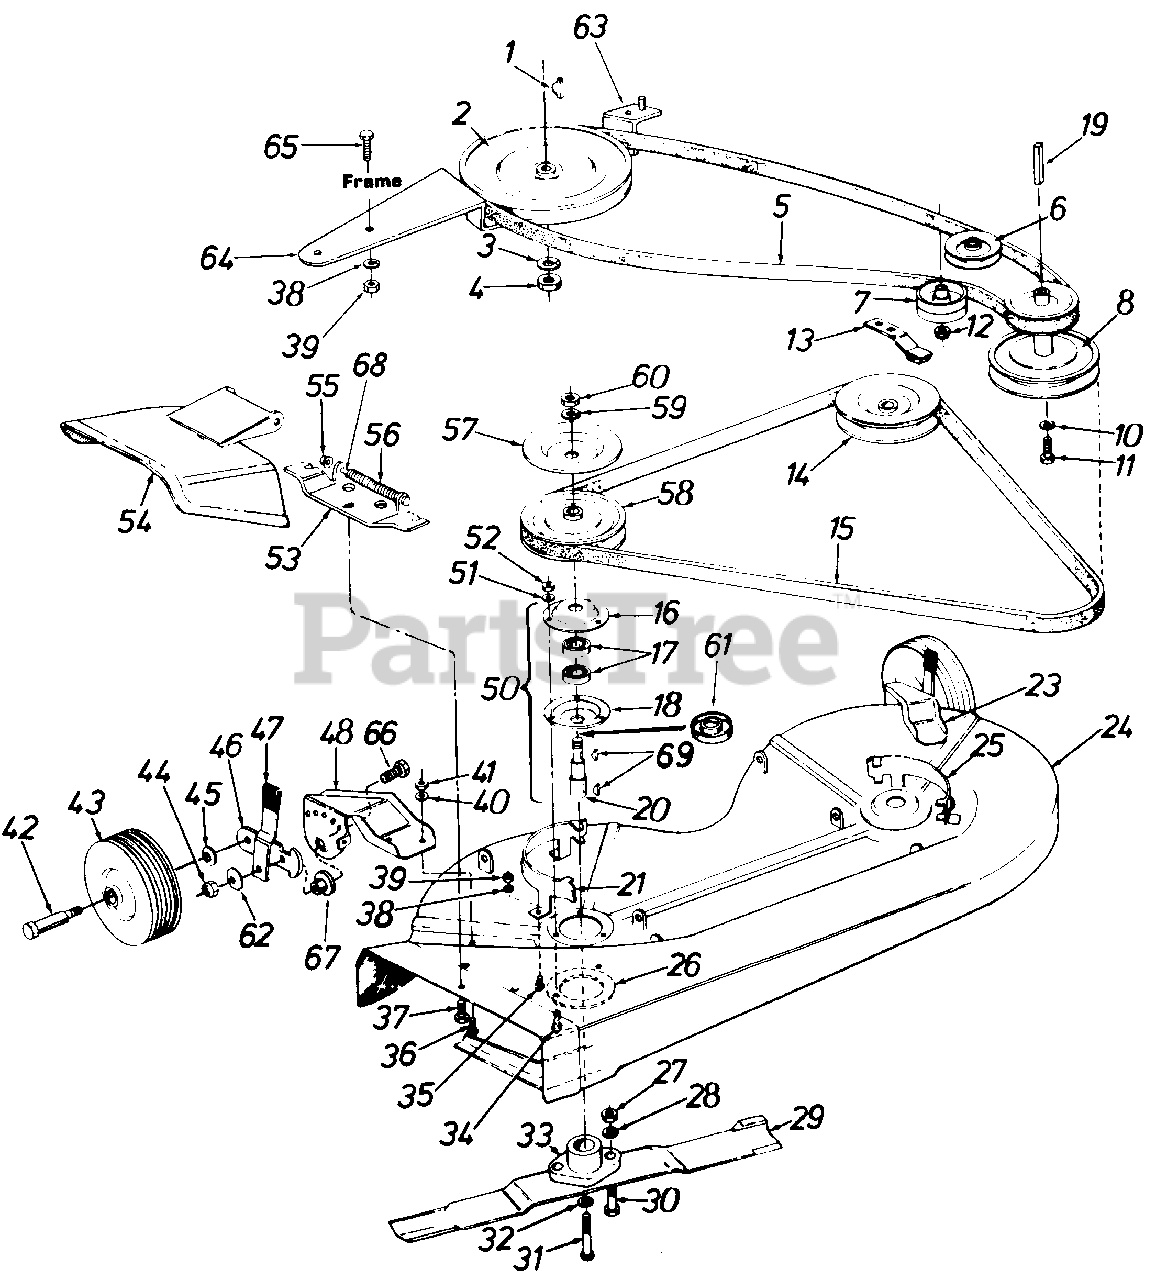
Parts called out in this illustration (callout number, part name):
1	#4 Hi-Pro Key 3/32 x 5/8" Dia.
2	Transmission Split Pulley .50 I.D.
3	L-Wash. 1/2" I.D.*
4	Hex Jam Nut 1/2-20 Thd.
5	"V" Belt 1/2 x 62" Lg.
6	"V" Idler 3.06 O.D.
7	"P" Flat Idler 2.75 O.D.
8	Two-Step Engine Pulley
10	L-Wash. 7/16" I.D.
11	Hex Bolt 7/16-20 x 1.0" Lg.
12	Hex Ins. L-Nut 3/8-24 Thd.
13	Blade Brake Ass'y.
14	Deck Pulley 4.75 O.D.
15	"V" Belt 21/32" x 64" Lg.
16	H ousi ng-Beari ng
17	Ball Brg. .787 I.D. x 1.85 O.D.
18	Housing-Bearing
19	Sq. Key 1/4" x 2.0" Lg.
20	Blade Spindle
21	Belt Guard R.H.-Deck
23	Wheel Bracket Ass'y.-L.H.
24	30" Deck Ass'y.
25	Belt Guard L.H.-Deck
26	Deck Reinforcement Plate
27	Hex Nut 5/16-24 Thd.
28	L-Wash. 5/16" I.D.
29	15" Blade
30	Hex Bolt 5/16-24 x 1.00"
31	Hex Bolt 3/8-24 x 1.50" H.T.
32	L-Wash. 3/8" I.D. H.D.
33	Blade Adapter
34	Hex Sems Scr. 5/16-18 x 1.00" Lg.
35	Hex Bolt 1/4-20 x .50" Lg.
36	Hex Bolt 1/4-20 x .50" Lg.
37	Hex Wash. Hd. Bolt Scr. 1/4-20 x .50" Lg.
38	L-Wash. 1/4" I.D.
39	Hex Nut 1/4-20 Thd.
40	L-Wash. 1/4" I.D.
41	Hex Nut 1/4-20 Thd.
42	Axle Bolt .498 Dia. x 1.53
43	Wheel Ass'y.-Comp. 5 x 1 .38
44	Hex Jam L-Nut 3/8-16 Thd.
45	Bell-Wash. .400 I.D. x .88 O.D.
46	Wheel Pivot Bar
47	Spring Lever Ass'y.
48	Wheel Brkt. Ass'y. R.H.
50	Blade Spindle Ass'y.-Comp.
51	L-Wash. 5/16" I.D.*
52	Hex Nut 5/16-18 Thd.
53	Adapter Plate Ass'y.
54	Chute Cover Ass'y.
55	Push Nut 1/4" Rod
56	Torsion Spring
57	Blade Brake-Disc
58	Deck Pulley 4.75 O.D.
59	L-Wash. 5/8n I.D.
60	Hex Jam Nut 5/8-11 Thd.
61	Bearing Shield
62	Bell-Wash.
63	Belt Keeper Ass'y.
64	Transmission Belt Guard
65	Truss Hd. Mach. Scr. 1/4-20 x.75" Lg.
66	Hex Bolt 3/8-16 x 1.00" Lg.
67	Shoulder Spacer
68	Hinge Pin
69	#6 Hi-Pro Key 5/32 x 5/8"
